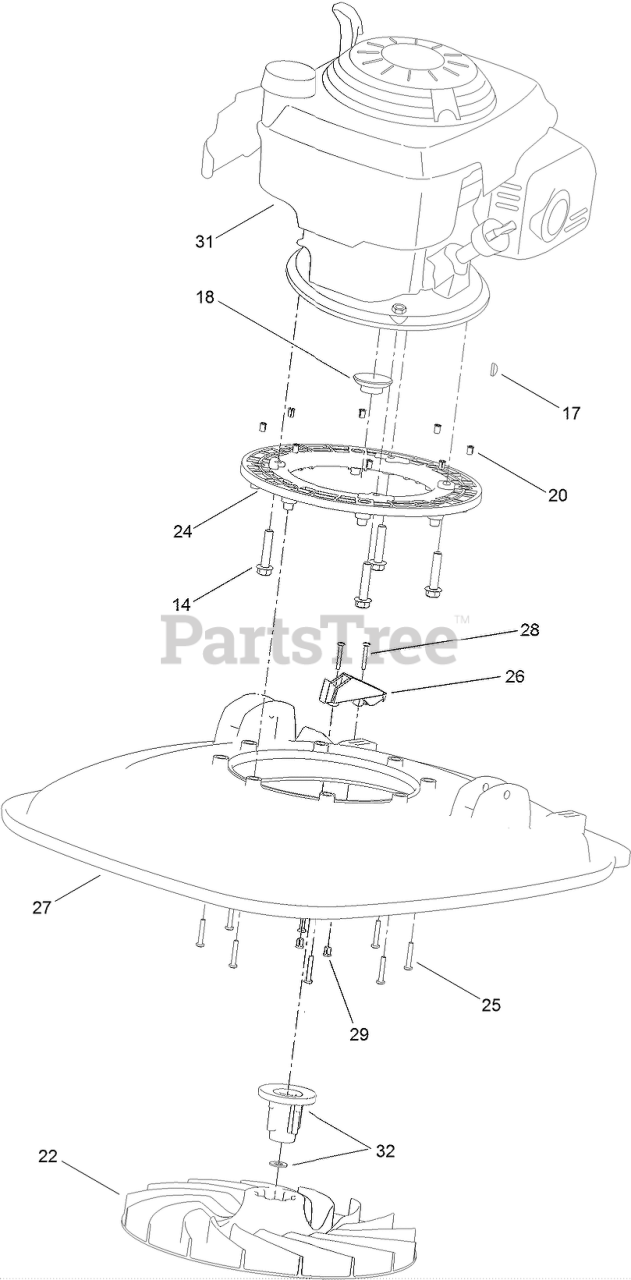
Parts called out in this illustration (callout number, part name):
14	SCREW-TAPTITE
17	KEY-WOODRUFF
18	PROTECTOR-SEAL, OIL
20	INSERT-BRASS
22	IMPELLER
24	FRAME-MOUNTING, ENGINE
25	SET-SCREW
26	BRACKET
27	DECK
28	SCREW
29	INSERT
31	Engine-Honda
32	DRIVE AND SPACER ASM
